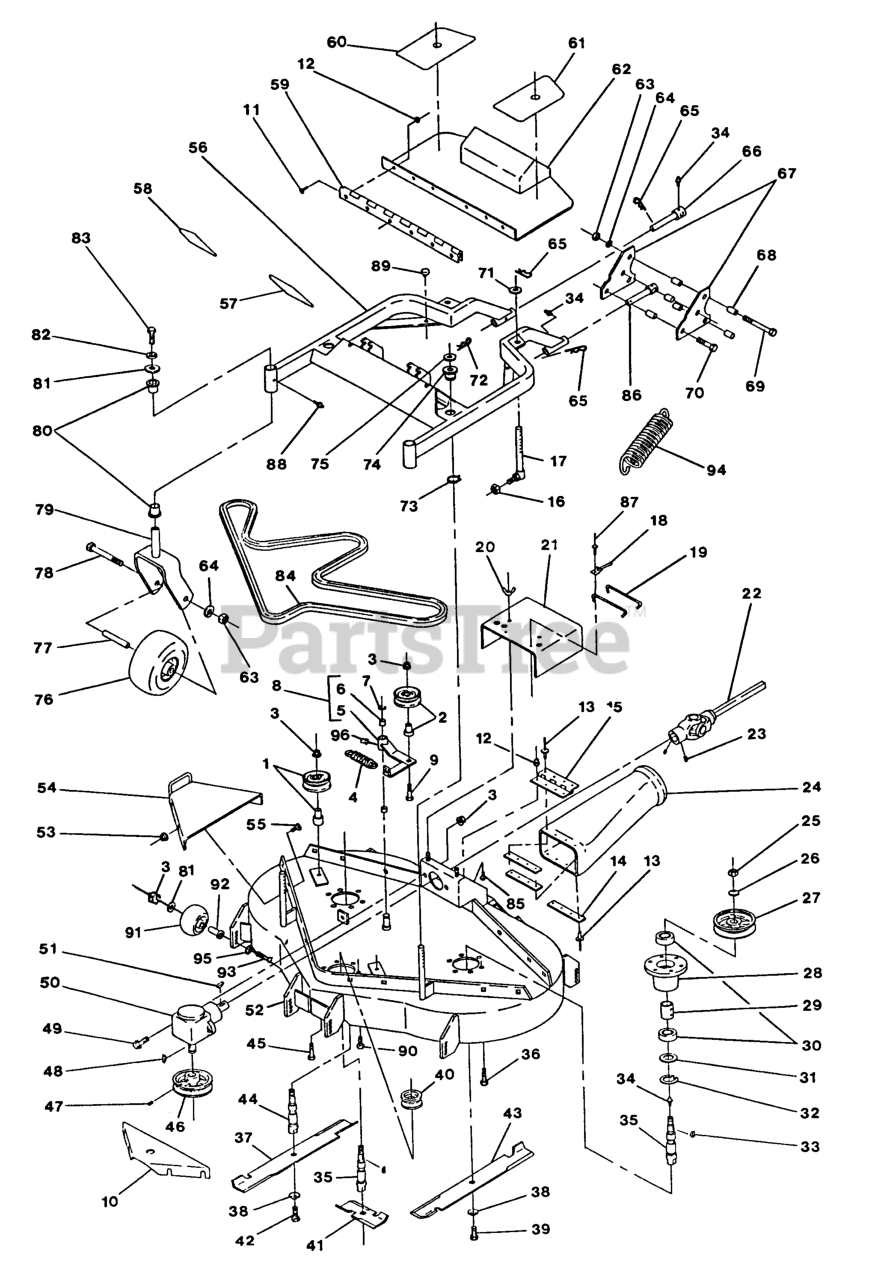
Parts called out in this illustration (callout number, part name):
1	KIT,IDLER & BUSHING
4	SPRING-IDLER, DECK
6	SLEEVE-BEARING
18	CLIP-DECK, HOLD UP ROD
20	WINGNUT-NYLOCK
22	PTO SHAFT,SHAFT HALF PNT
26	WASHER-SPRING
29	SPACER,BEARING
31	SEAL,MECHANICAL DUST
32	RING,SNAP WLDS N5000-244
36	SCRW,TPTTE HH
38	WASHER-SPRING
42	SCREW-CAP,HH
47	SCREW-SET
50	GEARBOX, PEERLESS
54	WLD,GUARD BELT
57	PAD,ANTI SKID UPPER LH
58	PAD,ANTI SKID UPPER RH
59	HINGE,FLOORPAN
60	PAD,ANTI SKID LOWER RH
65	PIN,HAIR COTTER
74	BUSHING-DECK
75	WASHER-FLAT
80	BEARING-FLANGED
84	BELT,DECK DRIVE
85	BOLT-CARR
87	Pop Rivet, Steel 3/16 X .250
91	ROLLER-SCALP, ANTI
92	BUSHING-ROLLER
